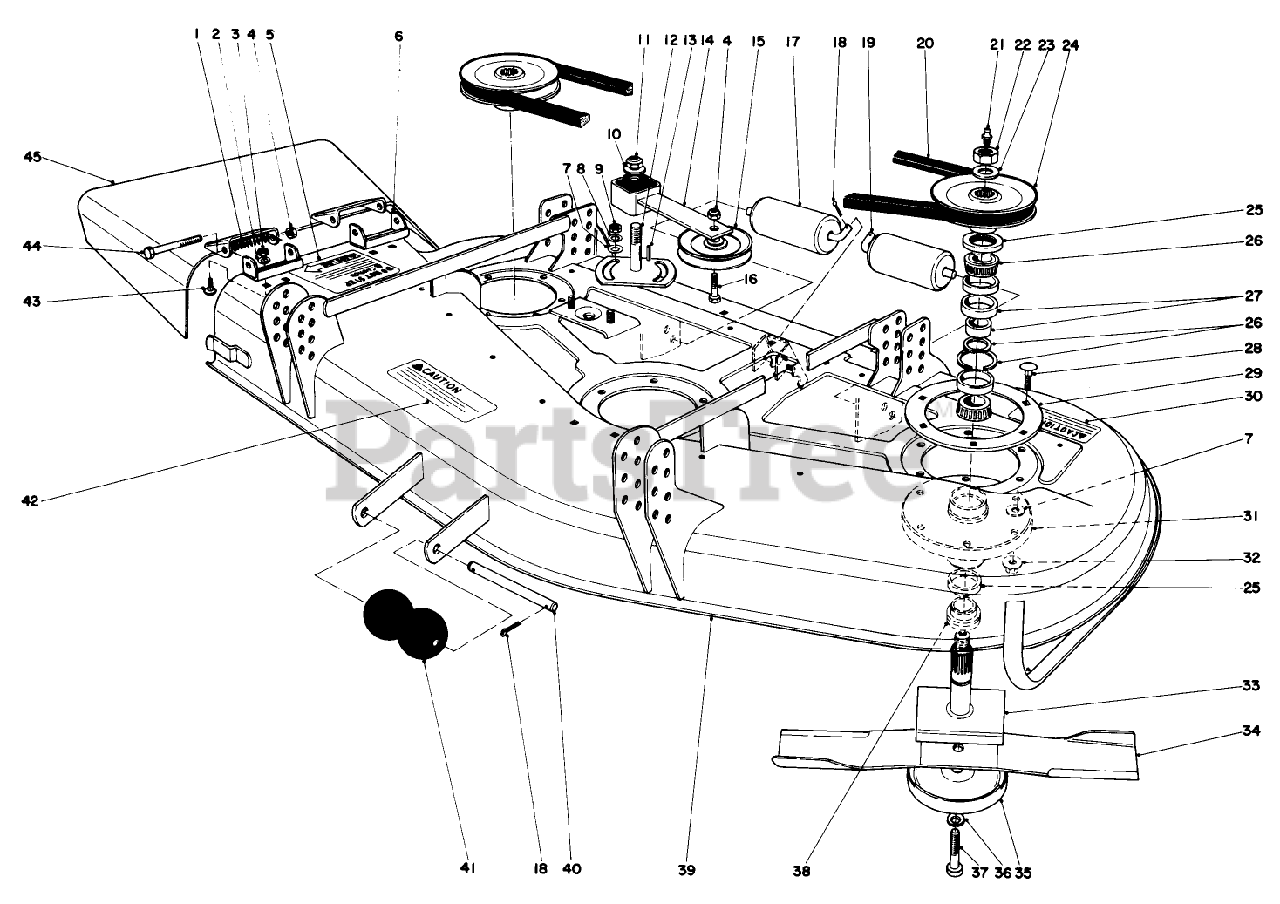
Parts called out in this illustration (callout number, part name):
1	SPRING
2	Lockwasher
3	NUT-HEX
4	NUT-HEX
5	Decal-Caution
6	Bracket-Pivot
7	WASHER-FLAT
8	WASHER-LOCK
9	NUT-JAM
10	WASHER-FLAT
11	NUT-LOCK, NI
12	PLATE-IDLER
13	KEY-SQUARE
14	IDLER ARM ASM
15	Idler Pulley
16	SCREW-HH
17	ROLLER-DECK
18	PIN-COTTER
19	SHAFT-ROLLER, REAR
20	V-BELT
21	FITTING-GREASE
22	NUT-HEX
23	Washer
24	PULLEY AND HUB ASM
25	SEAL-OIL
26	BEARING ASM
27	SPACER-SET, MATCHED
28	SCREW-CARR
29	SUPPORT-DECK, RING
30	DECAL-CAUTION, BLADE
31	Housing-Spindle
32	NUT-HF
33	SHAFT
34	Blade
35	Cup-Scalp
36	WASHER-LOCK
37	SCREW-BLADE
38	SPACER
39	GM 52 DECK WA RO
40	SHAFT-ROLLER
41	Roller
42	Decal-Caution
43	SCREW-CARR
44	SCREW-HH
45	Deflector
